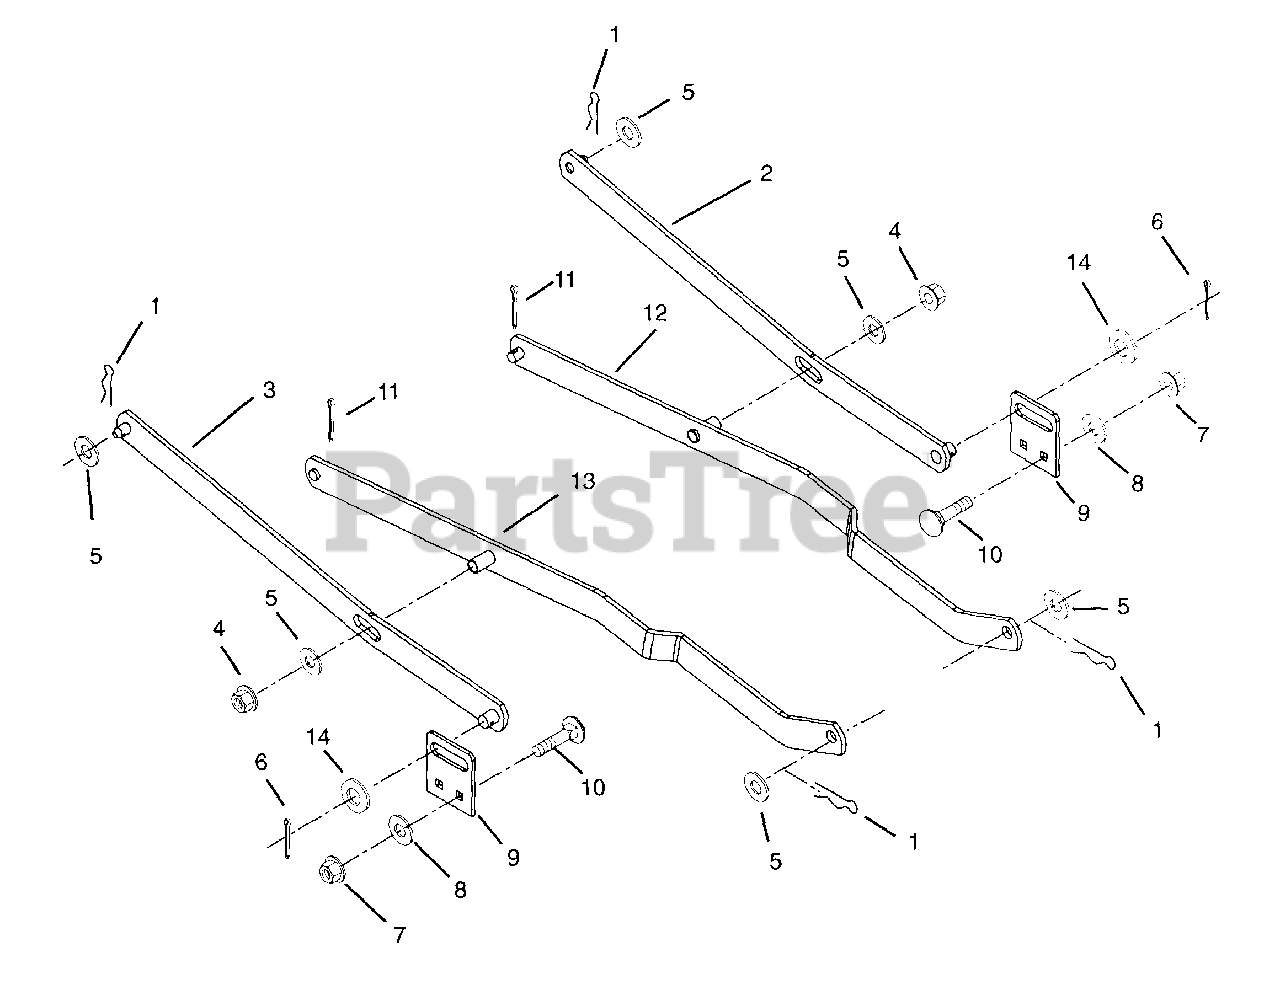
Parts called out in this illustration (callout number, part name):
1	PIN-HAIR-EXT .12X.31X2.37 YWZC
2	ARM, LIFT-LEFT REAR
3	ARM, LIFT-RIGHT REAR
4	@NUT-LK-CTR .62-11 YWZC
5	@WSHR-FL-STL.656X1.31X.095 YWZ
6	@PIN-CTR .16X1.25 EXTPRSQCT YZ
7	NUT-LK-CTR .375-16 YWZC
8	@WSHR-FL-STL.406X.812X.065 YWZ
9	ADJUSTOR, PAN
10	@BLT-RDHDSQNK .38-16X1.00 G2YZ
11	@PIN-CTR .12X1.25 EXTPRSQCT YZ
12	ARM, LIFT - LEFT FORWARD
13	ARM, LIFT - RIGHT FORWARD
14	@WSHR-FL-STL.531X1.06X.095YWZC
